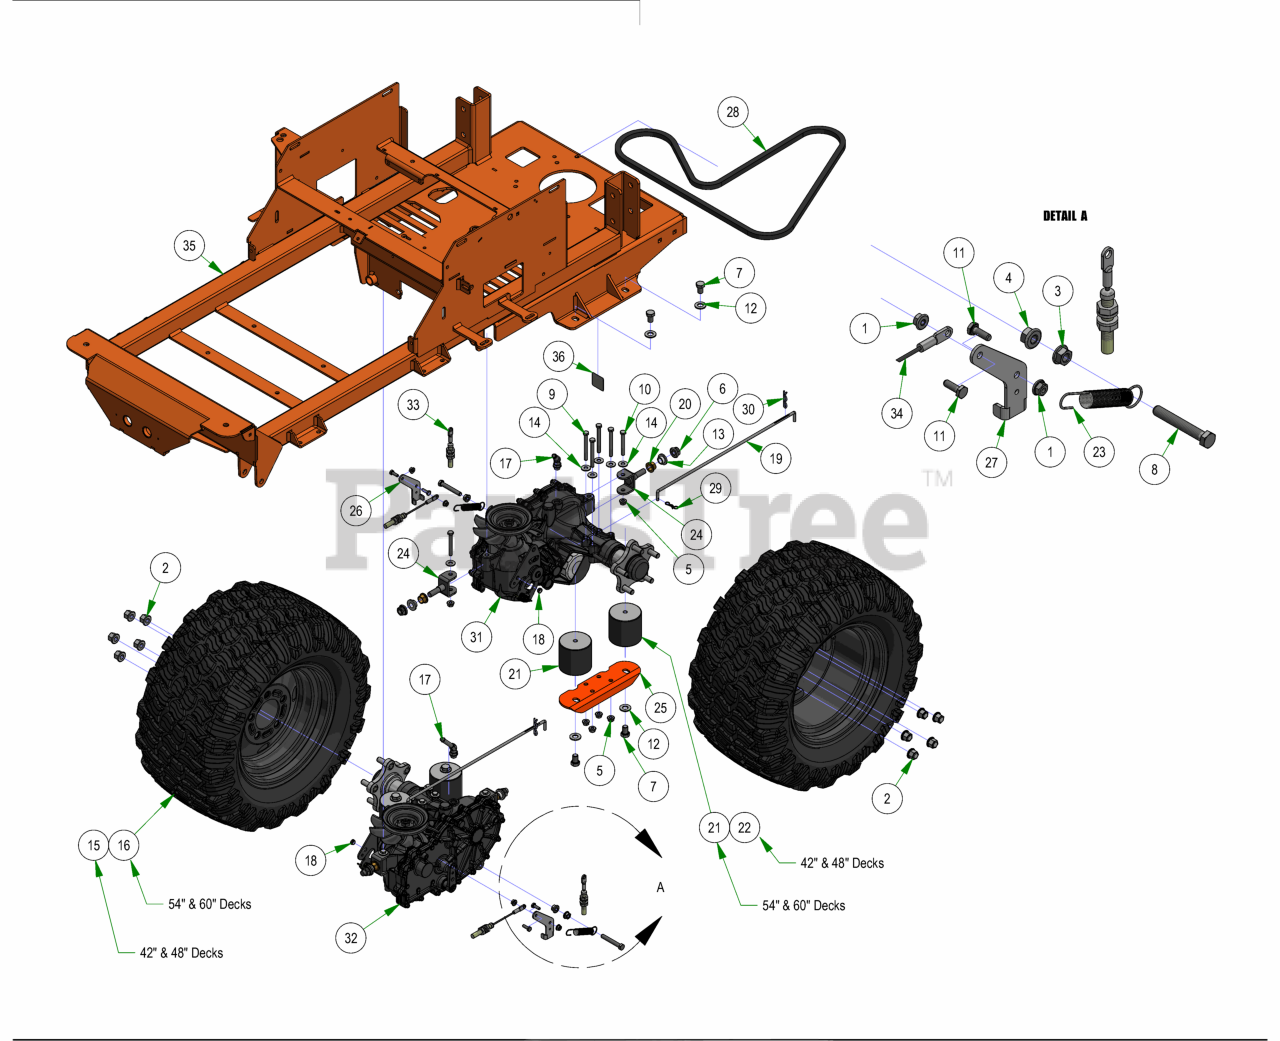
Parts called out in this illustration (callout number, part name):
1	1/4-20 NYL INSERT FLANGE LOCKNUT ZINC
2	Acorn Lug Nut
3	3/8-16 HEX SERRATED FLANGE NUT HARD/ZINC
4	3/8-16 NYLON INSERT FLANGE LOCKNUT (GR.F) ZINC
5	5/16-18 NYLON INSERT FLANGE LOCKNUT ZINC
6	1/2-13 NYLON INSERT FLANGE LOCKNUT ZINC
7	1/2-13 X 3/4 HEX CAP SCREW (GR.5) ZINC
8	3/8-16 X 2-1/2 HEX TAP BOLT (GR.5) ZINC Fully Threaded
9	5/16-18 X 3 HEX CAP SCREW (GR.5) ZINC
10	5/16-18 X 2-1/2 HEX CAP SCREW (GR.5) ZINC
11	1/4-20 X 3/4 HEX CAP SCREW (GR.5) ZINC
12	1/2 SAE FLAT WASHER (1-1/16" OD) GR.8 ZINC YELLOW
13	.525 ID SHOULDER WASHER NYLON
14	5/16 USS FLAT WASHER (7/8 OD) ZINC
15	23x9-12 Reaper Turf
16	23x11-12 Reaper Turf Assembly
17	ZT Fitting, 3/8 x 3/8 45 Degree, 4603-6-6
18	Drive Arm Transaxle Spacer
19	Neutral Rod
20	.627 ID X .753 OD X .500 LGTH X 1.000 FLG OD X .094 FLG THICK FLANGED BEARING OIL-IMPREG BRNZ
21	Vibration Mount-Green Dot
22	Vibration Mount- Red Dot
23	Brake Return Spring
24	Maverick Rear Transaxle Pivot Bracket
25	Rear Suspension Transaxle Mount
26	Brake Arm Ext (Left)
27	Brake Arm Ext (Right)
28	75.8" Pump Belt
30	Neutral Rod Clip
31	2025 LH 3400 Transaxle
32	2025 RH 3400 Transaxle
33	2021 Load Balanced Brake Cable 1
34	2021 Load Balanced Brake Cable 2
35	2025 Maverick Frame
36	Patent Decal
